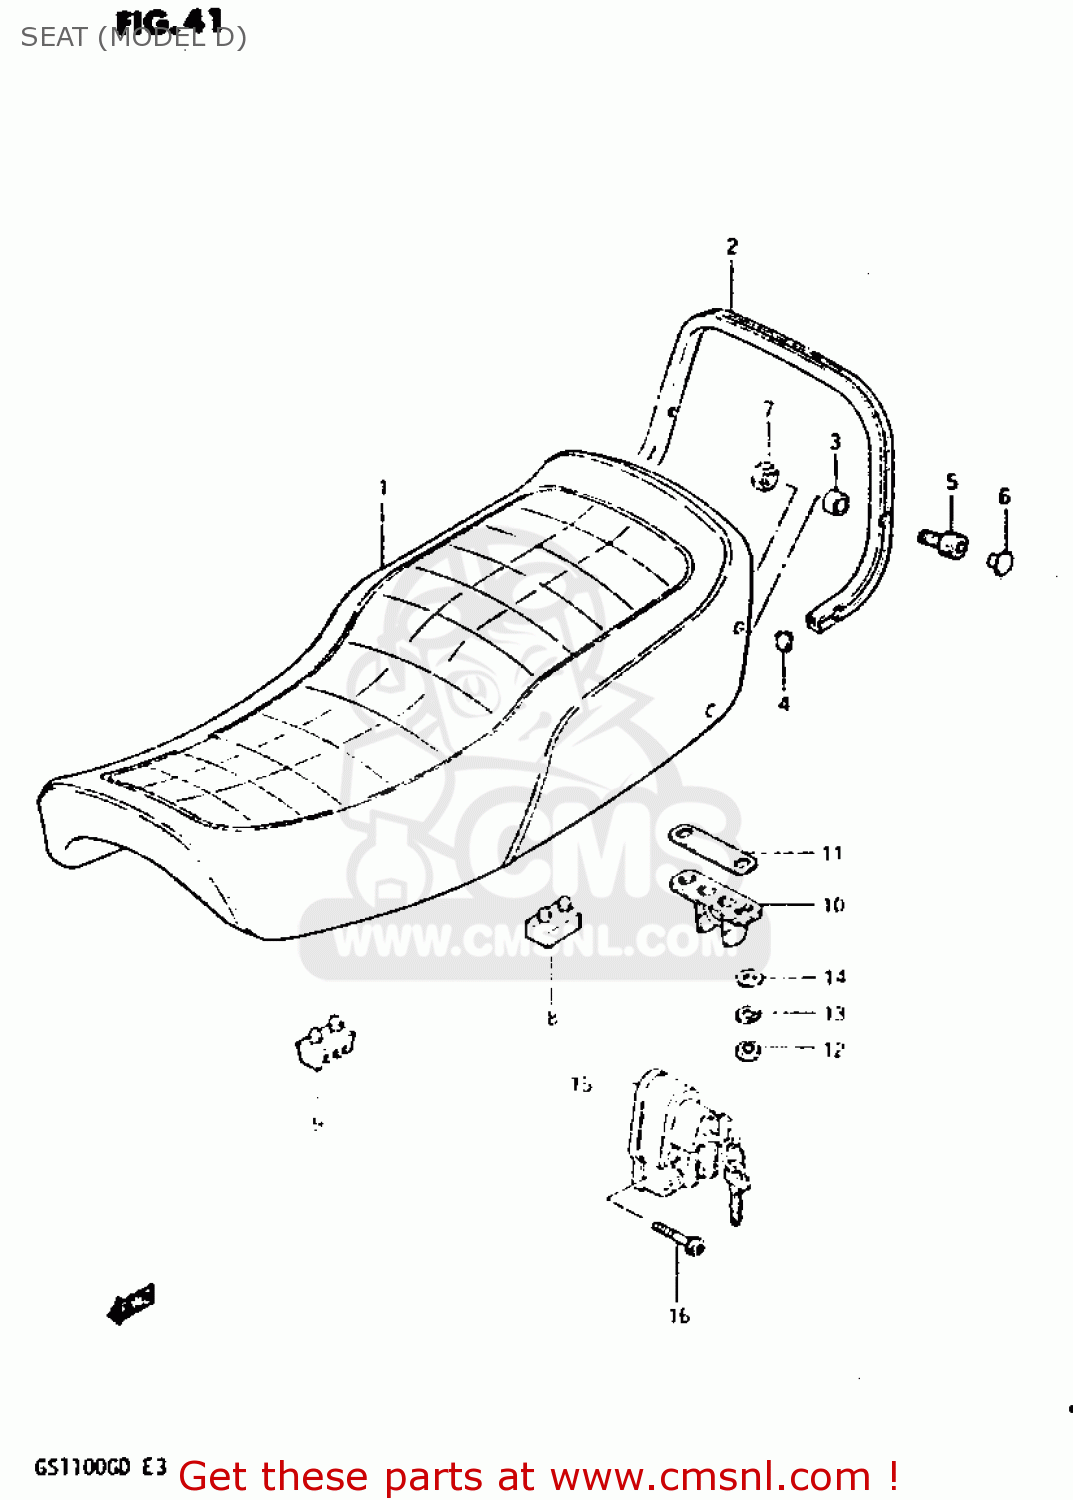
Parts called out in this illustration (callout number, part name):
1	SEAT ASSEMBLY
2	HANDLE,PILLION RIDER
3	SPACER,REAR
4	END,PILLION RIDER HAND
5	BOLT, REAR (8X30)
6	CAP(OD:14.5)
7	NUT
8	CUSHION
9	CUSHION,SUPPORT(50X25X32)
10	STRIKER,SEAT LOCK
11	SHIM,SEAT LOCK STRIKER
12	NUT 6MM
13	WASHER,LOCK
14	WASHER
15	LOCK ASSY,HELMET
16	BOLT
